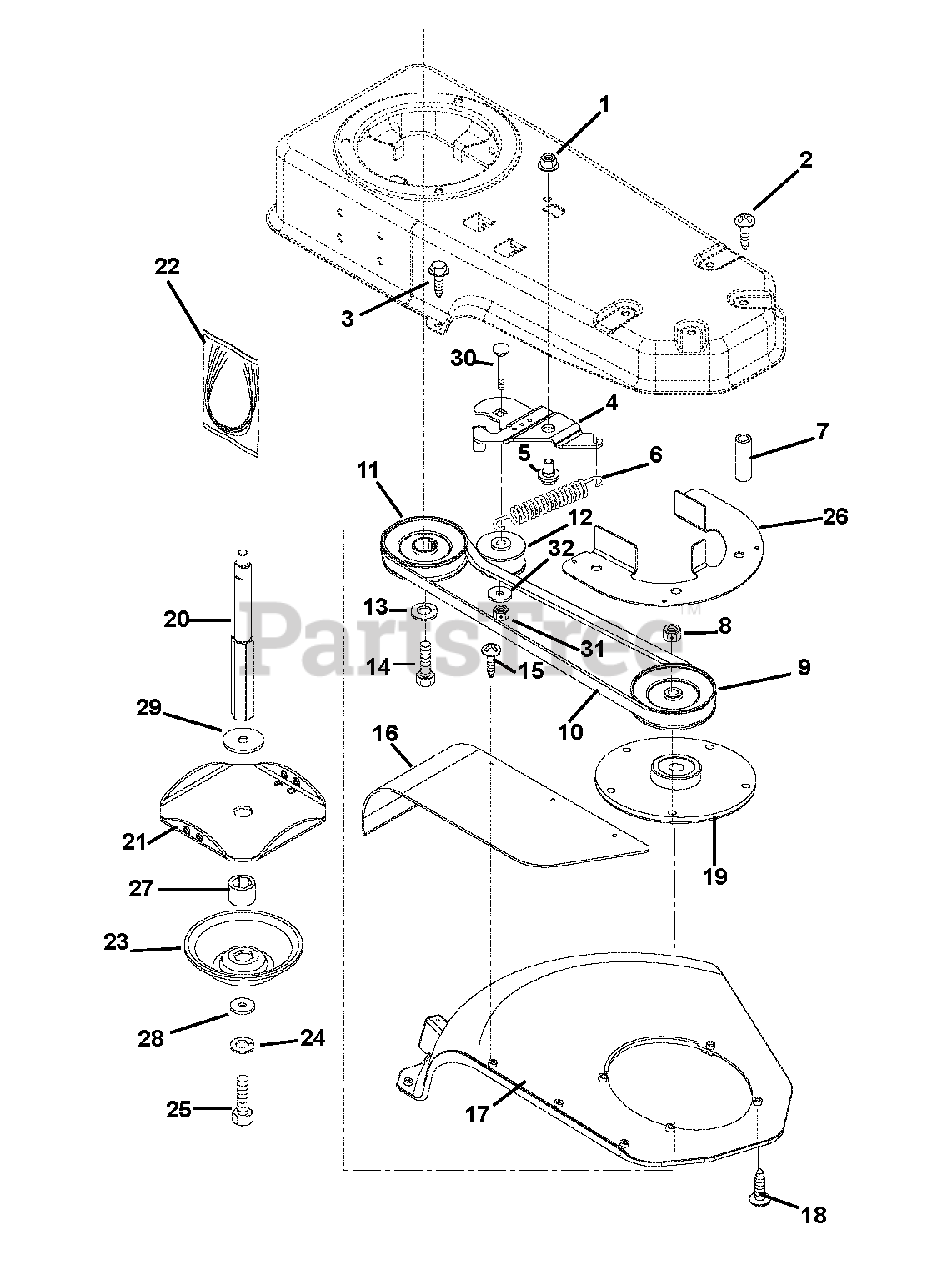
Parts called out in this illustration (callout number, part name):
1	Nut-Locking- Flange .38-16
2	Screw-Tapping .38-16 x 2.75
3	Screw-Tapping 10-24 x .75
4	Bracket-Idler
5	Bolt-Shoulder .38-16 x .135
6	Spring-Tension .035 x .45 x 2.75
7	Spacer-Jackshaft
8	Nut-Locking-Flange .38-24 Grade 5
9	Pulley-V 3.50 O.D. x .87 Wide (Cut)
10	Belt-V A-RMA 46.06 x .50
11	Sheave-Engine 3.50 O.D. x .87 Wide
12	Idler-Flat 1.88 O.D. x .75 Wide
13	Washer-Locking .38 x .94 Regular
14	Bolt-Hex .38-24 x 1.00
15	Screw-Tapping 10-16 x .625 Hex Washer Head
16	Guard-Debris
17	Shield-Trimmer
18	Screw-Tapping 10-24 x .75
19	Housing-Jackshaft
20	Shaft-Cutter-Hex
21	Disc-Cutter
22	Line-Cutter 18" (Pack of 6)
23	Guide-Height-Hex
23	Guide-Height-Long Life
24	Washer-Locking .31 x .078
25	Bolt-Hex .31-18 x .75 Grade 5
26	Finger-Belt
27	Spacer-Hex
28	Washer-Flat-Steel .344 x 1.13 x .135
29	Shield-Dust
30	Bolt-Round Head Short Square Neck .38-16 x 1.50 Grade 5
31	Nut-Locking-Center .38-16
32	Washer-Flat-Steel .406 x .812 x .065
